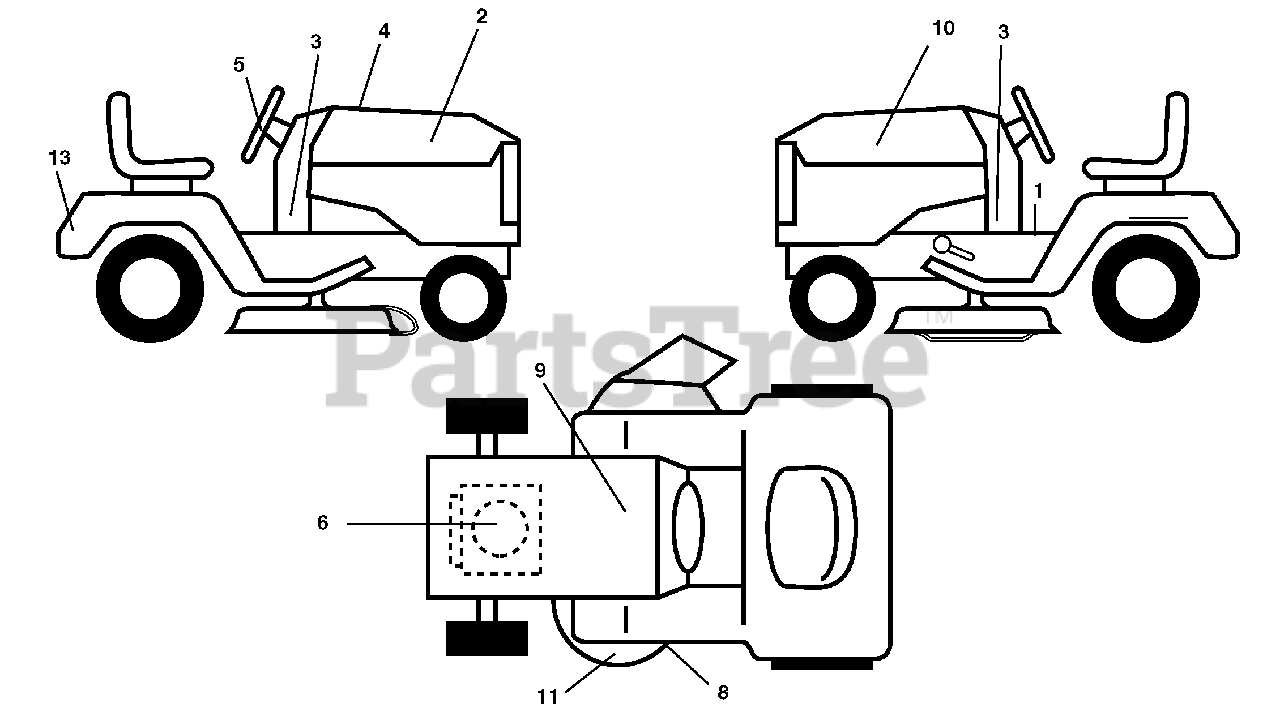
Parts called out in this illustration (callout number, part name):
1	Decal, Operator's
2	Decal, Hood RH
3	Decal, Dash Lower
4	Decal, Replacement
5	Decal, Strg Whl
6	Decal, Engine HP
8	Decal, Mower Sch.
9	Decal, Battery Dnge/Poi
10	Decal, Hood LH
11	Decal, Mower Caution
13	Decal, Fender
13	Decal, Bypass
13	Pad, Footrest, RH
13	Pad, Footrest, LH
13	Manual, Operator's E&SP
13	Manual, Parts
